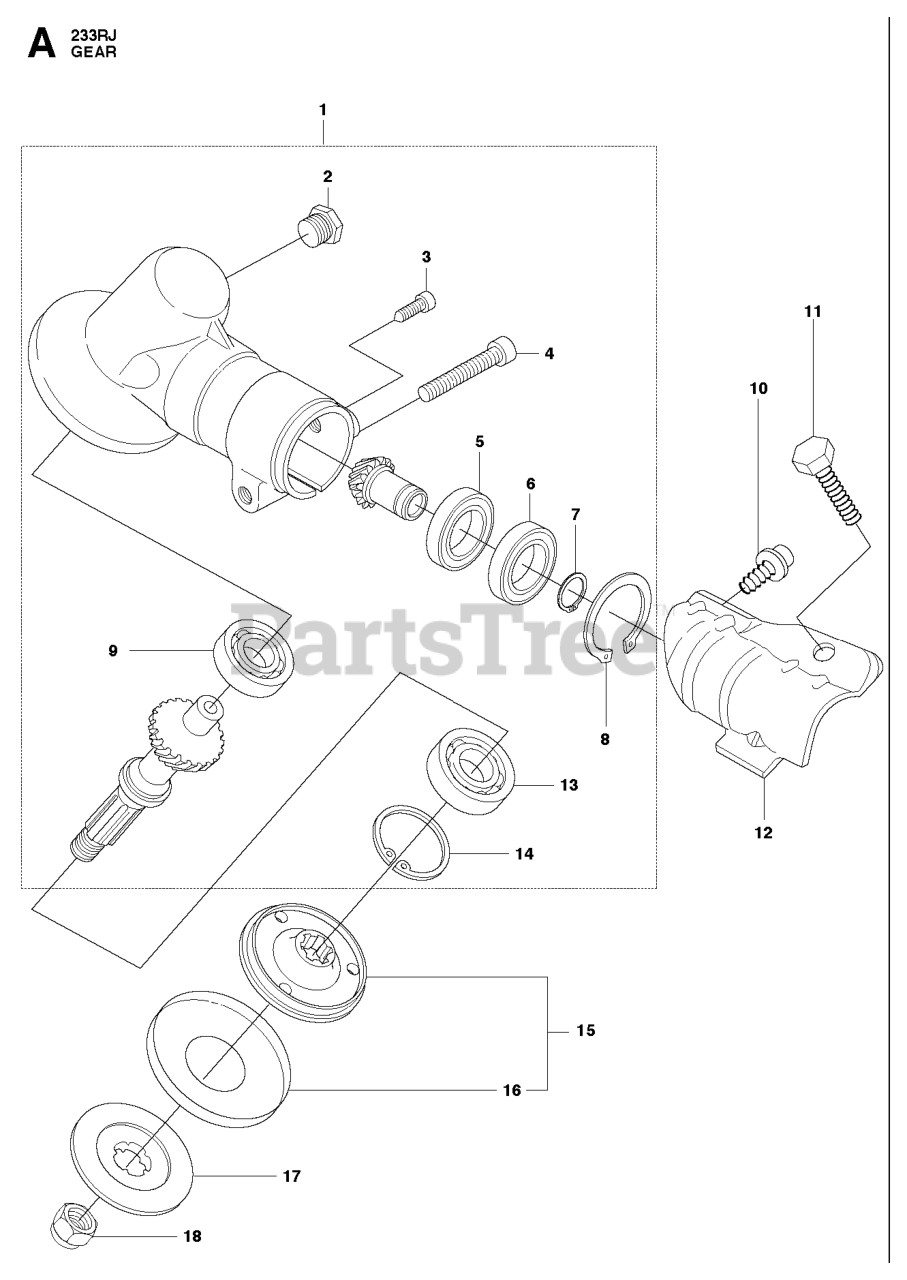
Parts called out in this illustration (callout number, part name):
1	GEARCASE-A
3	SCREW
4	SCREW
5	BALL BEARING 24X9X1/609ZR
7	RETAINING RING
8	RETAINING RING
9	BALL BEARING 8X22X7/608Z
10	SCREW
11	SCREW M6S 6X20
12	RP BRACKET TRIMMER GUARD
13	BEARING
14	RETAINING RING SGH 28
15	DRIVE DISC
16	WASHER
17	SUPPORT FLANGE
18	GEARHEAD NUT - BRUSHCUTTER
